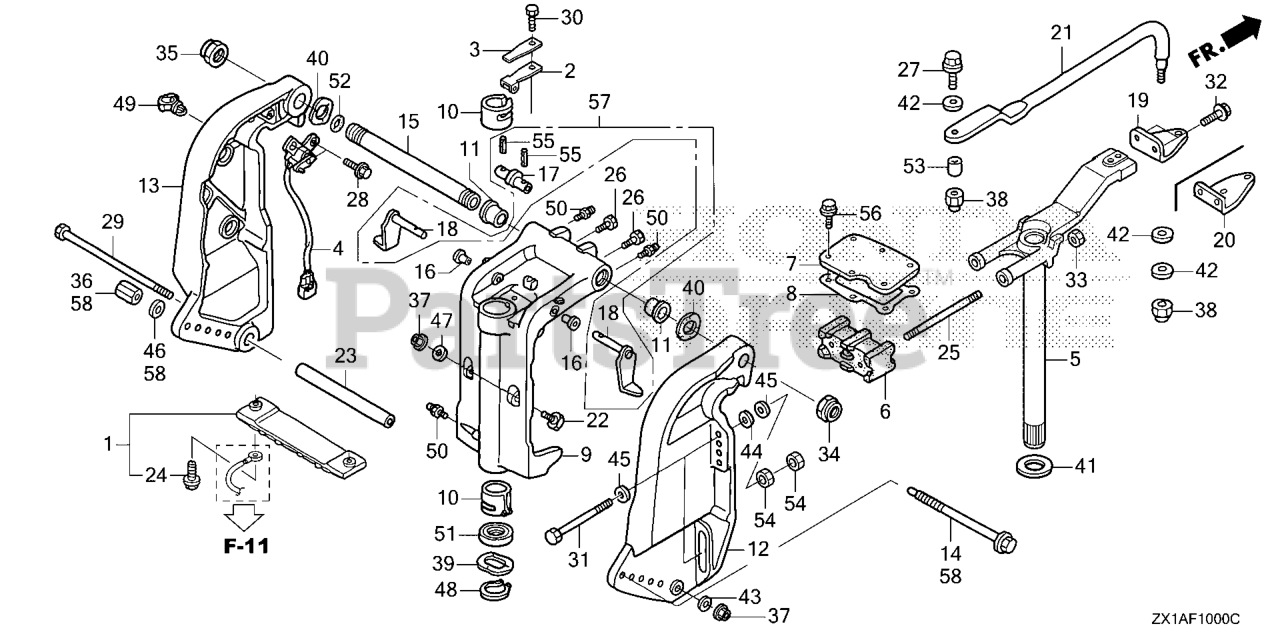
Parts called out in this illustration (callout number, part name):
1	METAL KIT, ANODE Use from Frame SN 4800343.
2	SPRING, CLICK
3	SPRING, CLICK ASSIST
4	SENSOR ASSY., TRIM ANGLE
5	FRAME, MOUNTING
6	MOUNT, RUBBER (UPPER)
7	HOLDER, MOUNTING (UPPER)
8	GASKET, MOUNTING HOLDER (UPPER)
9	CASE, SWIVEL *NHB14M* (AQUA MARINE SILVER METALLIC)
9	CASE,SWIVEL*NH565*
10	LINER, SWIVEL CASE
11	BUSH, SWIVEL CASE
12	BRACKET, R. STERN *NHB14M* (AQUA MARINE SILVER METALLIC)
12	BRACKET,STE*NH565*
13	BRACKET, L. STERN *NHB14M* (AQUA MARINE SILVER METALLIC)
13	BRACKET,STE*NH565*
14	ROD, ADJUSTING
15	SHAFT, TILTING
16	BUSH, TILT ARM
17	BRACKET, TILTING
18	STOPPER, TILT
19	PLATE, STEERING
20	PLATE, STEERING
21	ROD, STEERING
22	RECEIVER, THRUST
23	COLLAR, CYLINDER (LOWER)
24	BOLT, FLANGE (6X23) Use from Frame SN 4800343.
25	BOLT, STUD (12X150)
26	BOLT (1/4-28UNF)
27	BOLT (3/8-24UNF)
28	BOLT, FLANGE (6X20) (ENGINE NO.)
29	BOLT, HEX. (10X235)
30	BOLT, HEX. (6X14)
31	BOLT, HEX. (12X119)
32	BOLT, FLANGE (10X25)
33	NUT, FLANGE (12MM)
34	NUT, SELF-LOCK (7/8-14UNF)
35	NUT, SELF-LOCK (M25X2.0)
36	NUT, ADJUSTER ROD
37	NUT, FLANGE (10MM)
38	NUT, SELF-LOCK (3/8-24UNF)
39	WASHER, WAVE (40MM)
40	WASHER, WAVE (26MM)
41	WASHER, THRUST (34MM)
42	WASHER (10MM)
43	WASHER, PLAIN (10MM)
44	WASHER, PLAIN (12MM)
45	WASHER, PLAIN (12MM)
46	WASHER, PLAIN (12MM)
47	WASHER, PLAIN (10MM)
48	CIRCLIP (OUTER) (39MM)
49	CLIP, WIRE HARNESS
50	NIPPLE, GREASE
51	OIL SEAL (39.5X52X6) (ARAI)
52	O-RING (15.54X2.26)
53	COLLAR, STEERING ROD
54	NUT, HEX. (12MM)
55	PIN, SPRING (2.5X20)
56	BOLT, FLANGE (8X35)
57	STOPPER KIT, TILT
58	ROD, ADJUSTING
